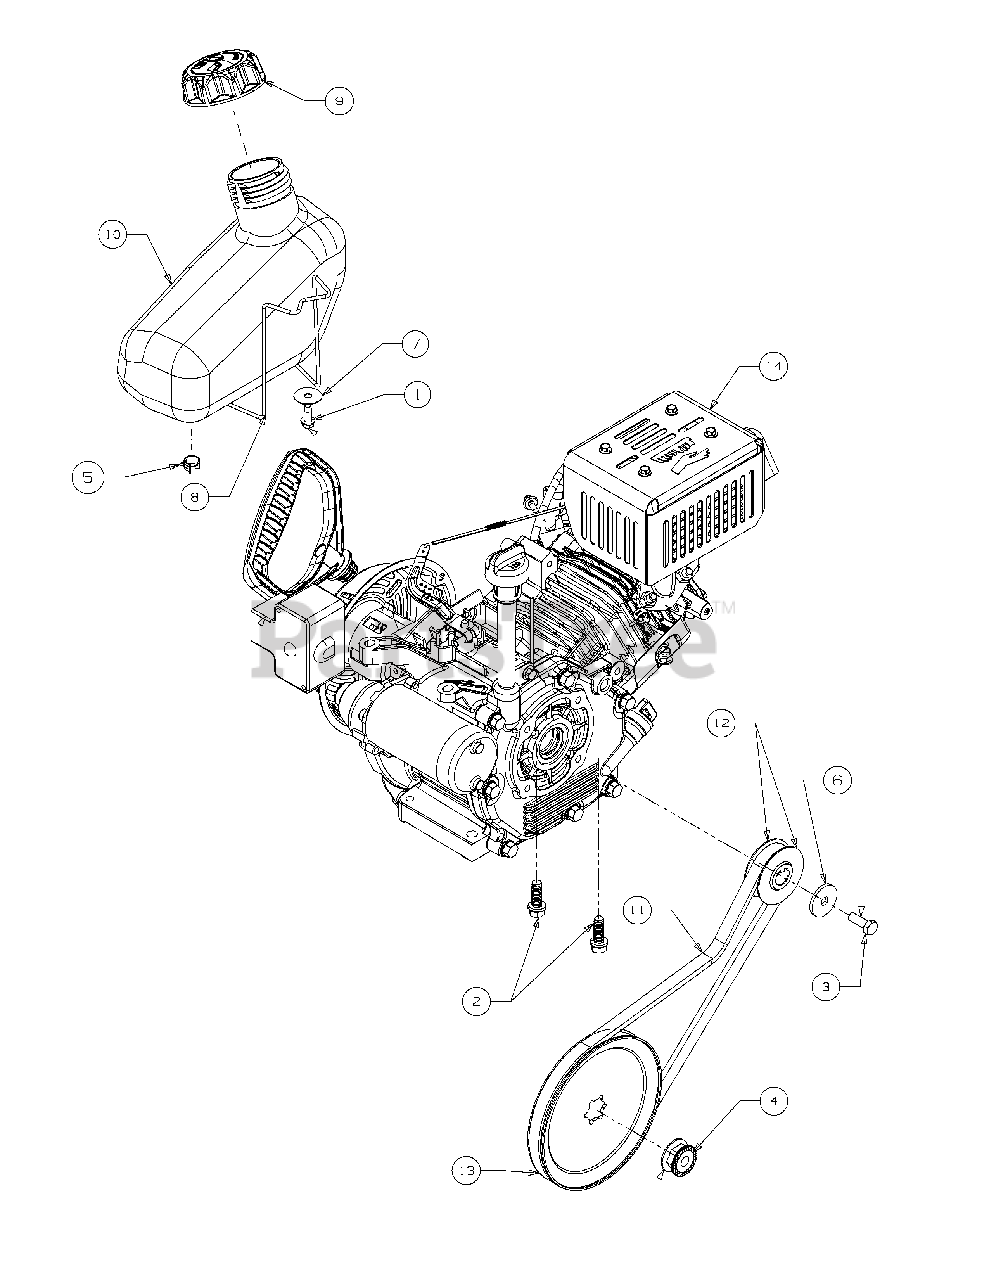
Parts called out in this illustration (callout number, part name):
1	Screw 1/4-10:.625
2	Screw-Hex
3	Screw-Hex Cap 5/1
4	Nut-Flang E W/Hu
5	Hose Clamp 1/20
6	Washer-5/16 X 1.25
7	Washer-Flat
8	Support-Wire Gas T
9	Cap-Fuel Thread Ve
10	Tank-Fuel 2 Qt
11	Belt-V Type
12	Half Pulley
13	Pulley-Auger
14	Engine-Complete
